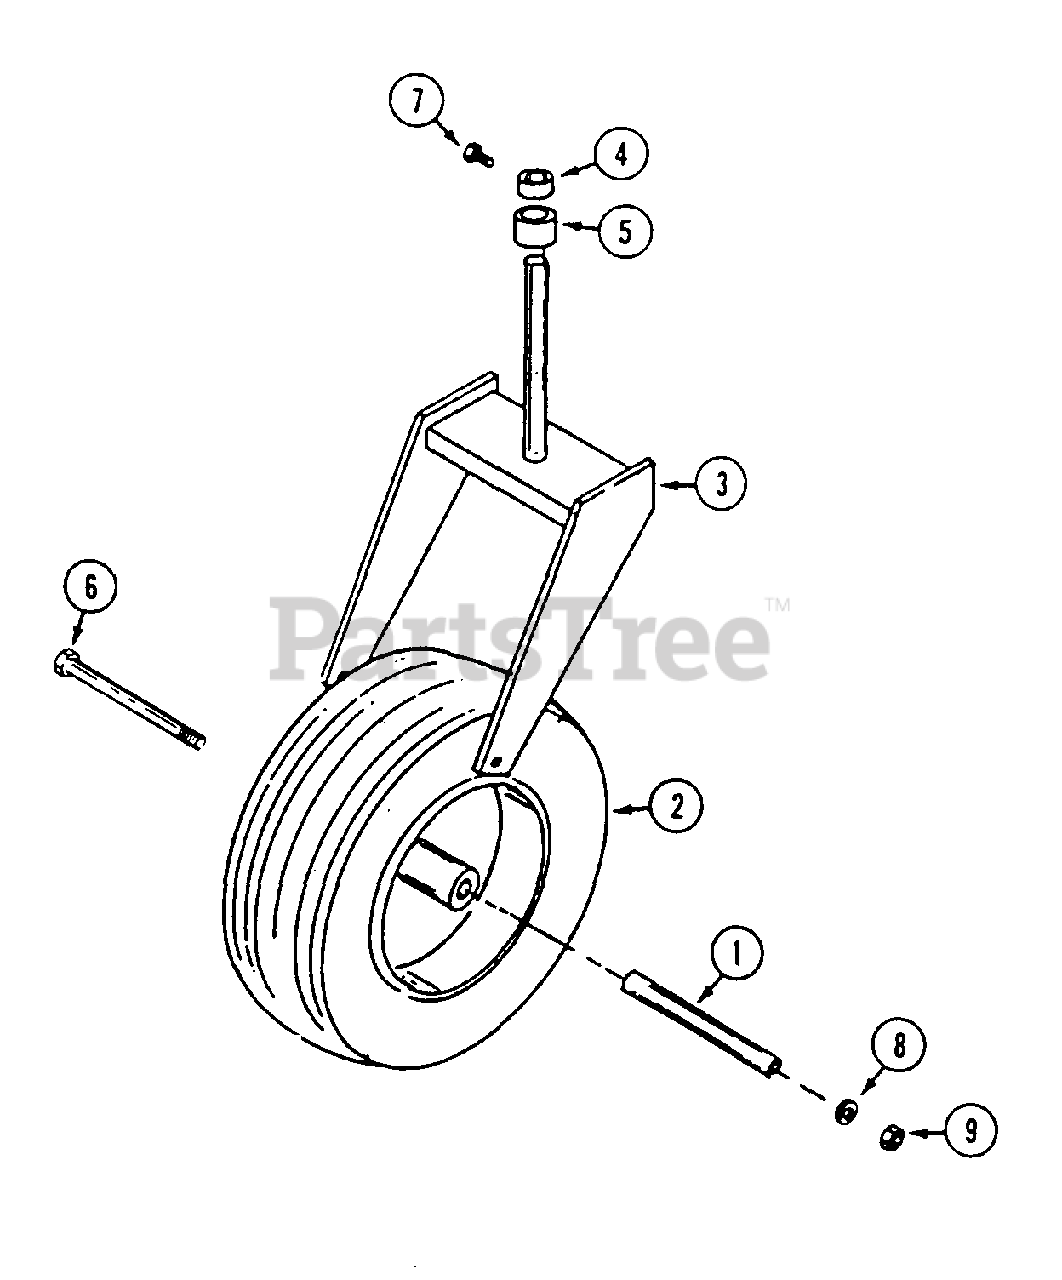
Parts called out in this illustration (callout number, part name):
2	WHEEL ASSEMBLY - tail 16 x 6.50 - 8
3	FORK - tail wheel
4	COLLAR - set 1"
5	SPACER - tail wheel fork
6	BOLT - 1/2" - 13 x 9-1/2"
7	SCREW - set 5/16" - 18 x 1/2" square head
8	LOCKWASHER - 1/2"
9	NUT - 1/2" - 13
